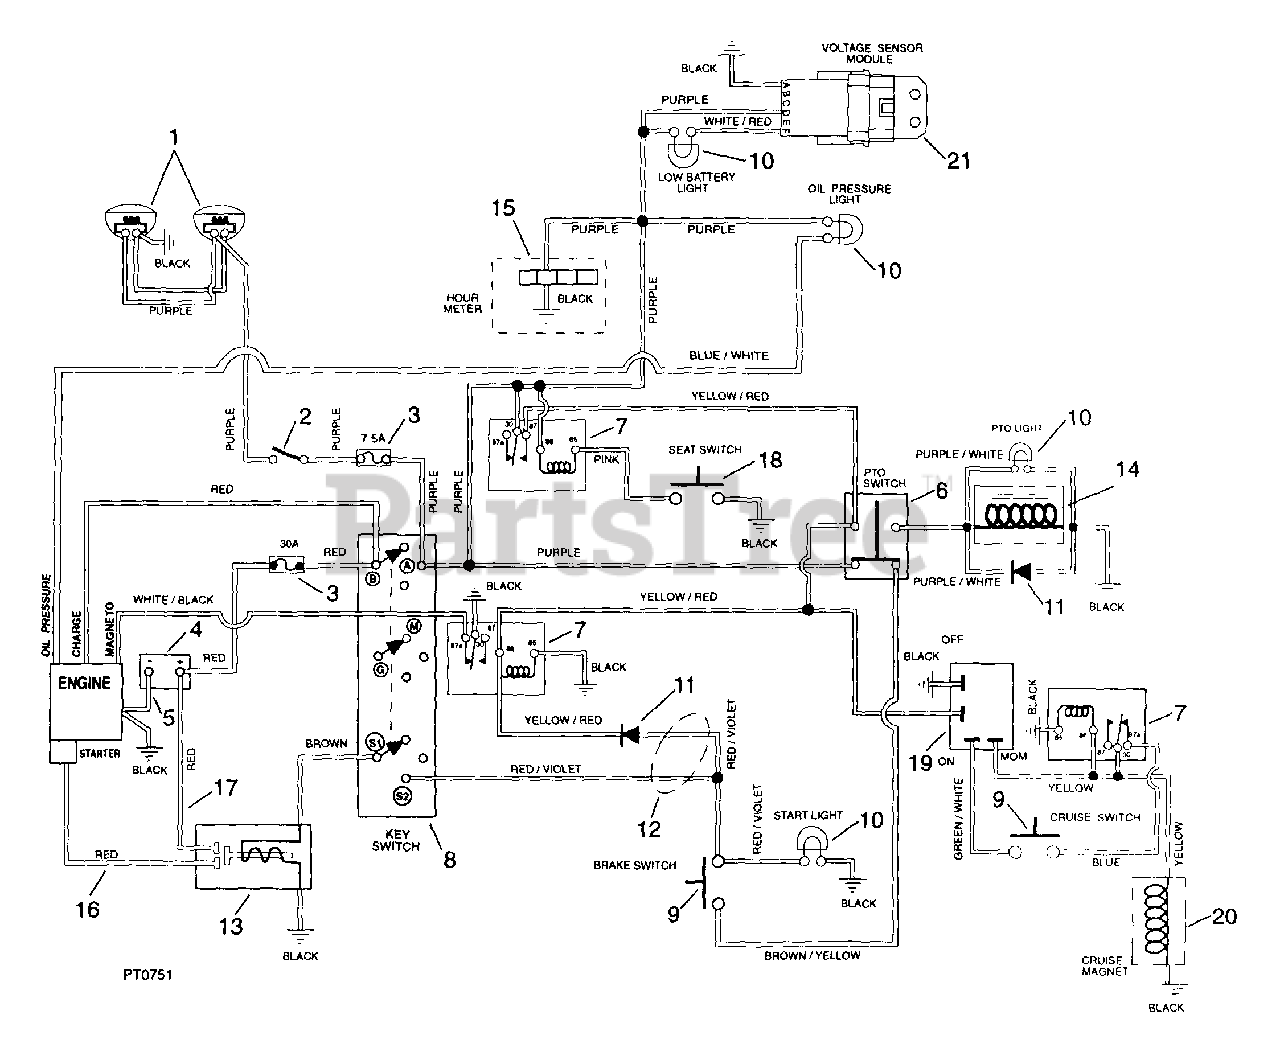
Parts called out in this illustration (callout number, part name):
1	HEADLIGHT- RH
1	HEADLIGHT- LH
2	SWITCH - LIGHT
3	7.5 AMP Fuse
3	30 AMP Fuse
4	BATTERY W/TUBE
5	GROUND CABLE .31X22.00X.31
6	PTO KNOB/ SWITCH ASSY
7	RELAY
8	KEY SWITCH
9	SWITCH- SINGLE POLE N.O.
10	#194 Bulb
11	MOLDED DIODE PLUG 1 AMP
12	WIRE HARNESS - 1540H KOHLER
13	SOLENOID
14	ELECTRIC CLUTCH/BRAKE (3.4AMP)
15	HOURMETER KIT- SIERRA
16	START CABLE 22"
17	STARTER CABLE 6.75"
18	SWITCH- SEAT
19	SWITCH - CRUISE
21	MODULE - VOLTAGE SENSOR
